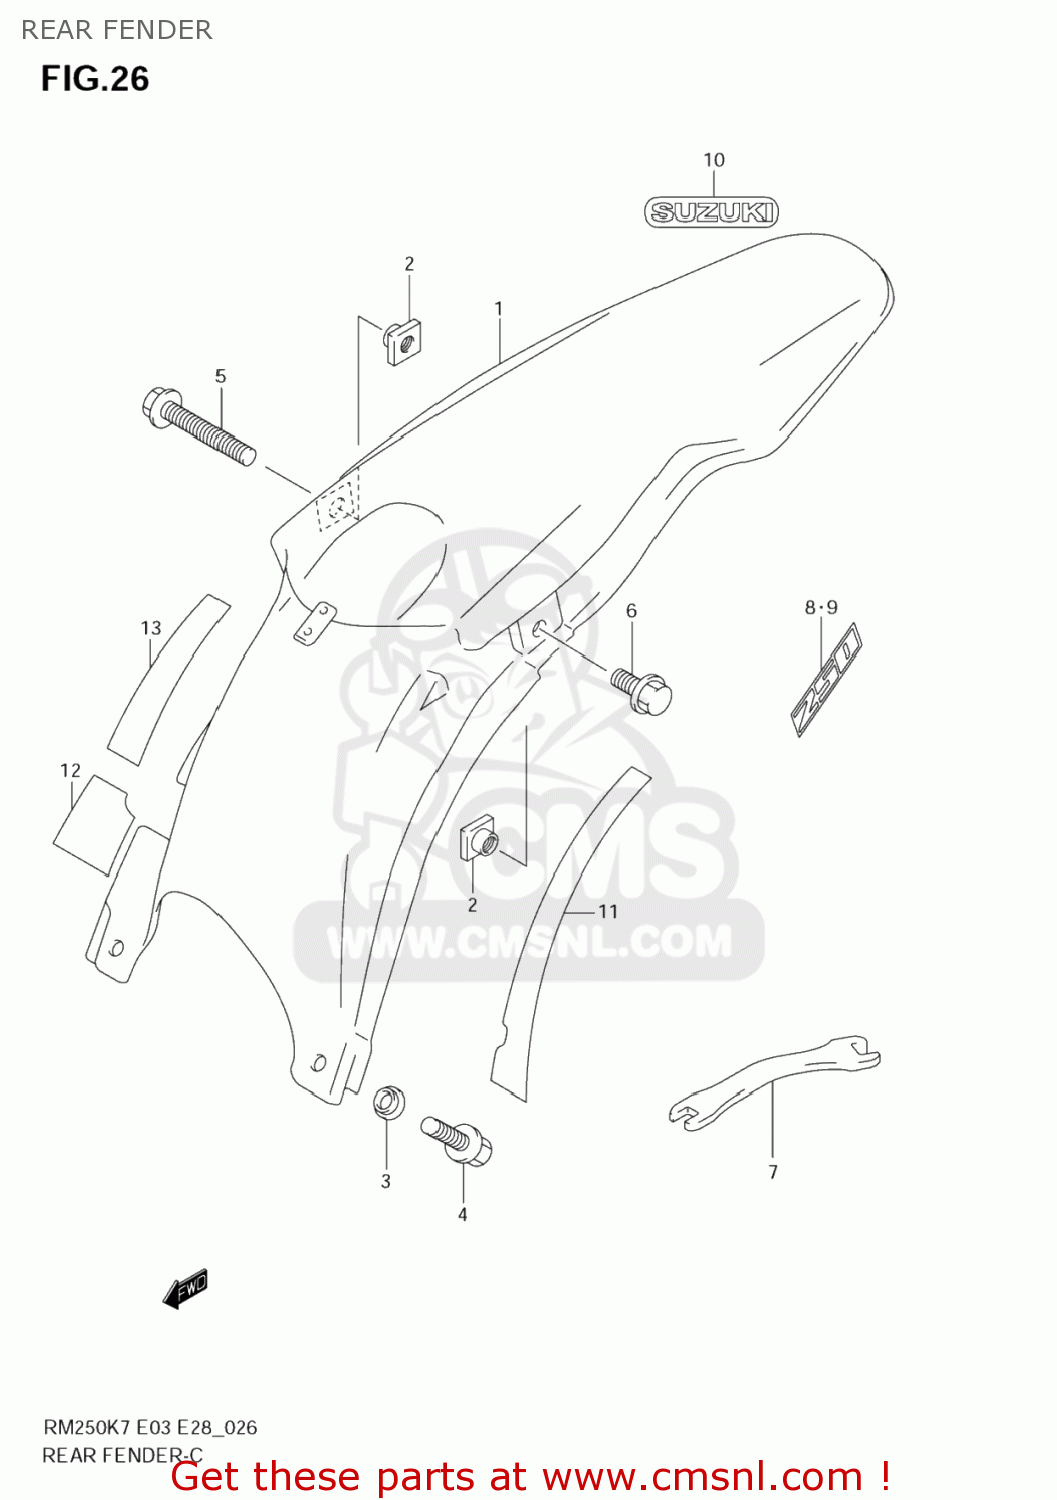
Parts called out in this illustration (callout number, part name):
1	FENDER,RR
2	NUT
3	WASHER
4	BOLT,6X20
5	BOLT(6X35)
6	BOLT(6X16)
7	OPEN SPANNER(6.4X6.8)
8	TAPE,RR FENDER,R
9	TAPE,RR FENDER,L
10	EMBLEM,RR
11	CUSHION,RR FENDER NO.1
12	CUSHION,RR FENDER NO.2
13	CUSHION,RR FENDER NO.3
